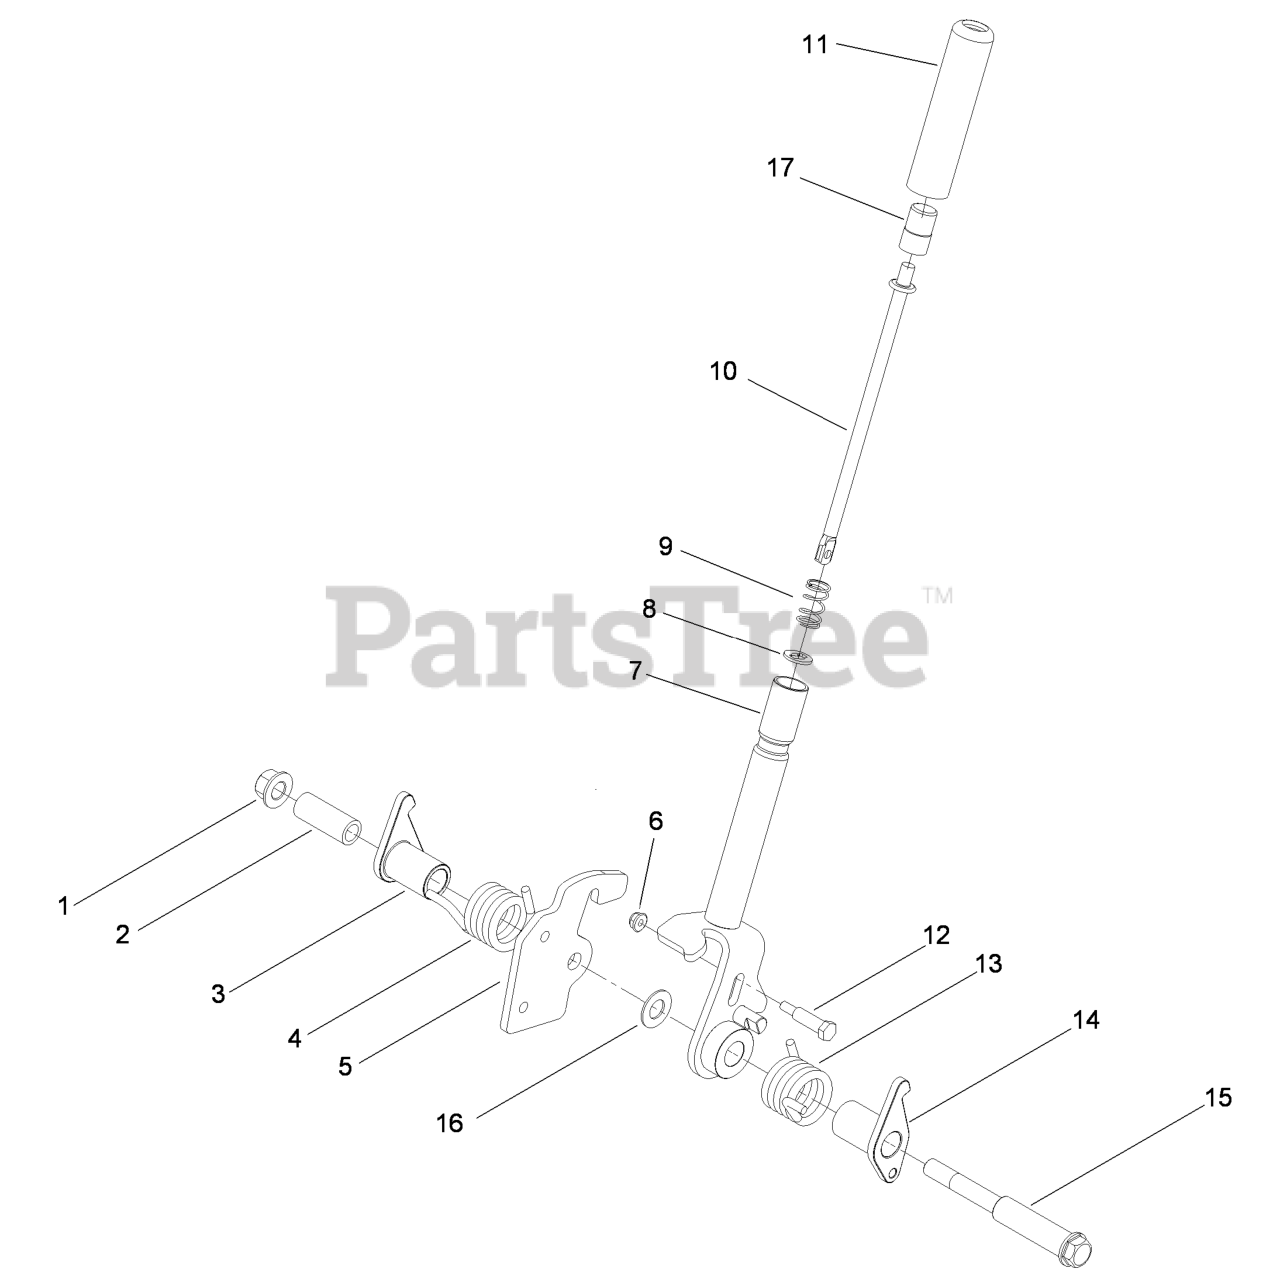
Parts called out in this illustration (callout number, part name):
1	Nut-Lock 1/2-13
3	ARM-BRAKE, LH
4	SPRING-TORSION, RH
5	PLATE-LATCH
7	BRAKE HANDLE ASM
8	WASHER-SPECIAL
9	SPRING-COMPRESSION
10	ROD-RELEASE, BRAKE
12	BOLT-SHOULDER
13	SPRING-TORSION, LH
14	ARM-BRAKE, RH
15	BOLT-SHOULDER
16	WASHER-FLAT
